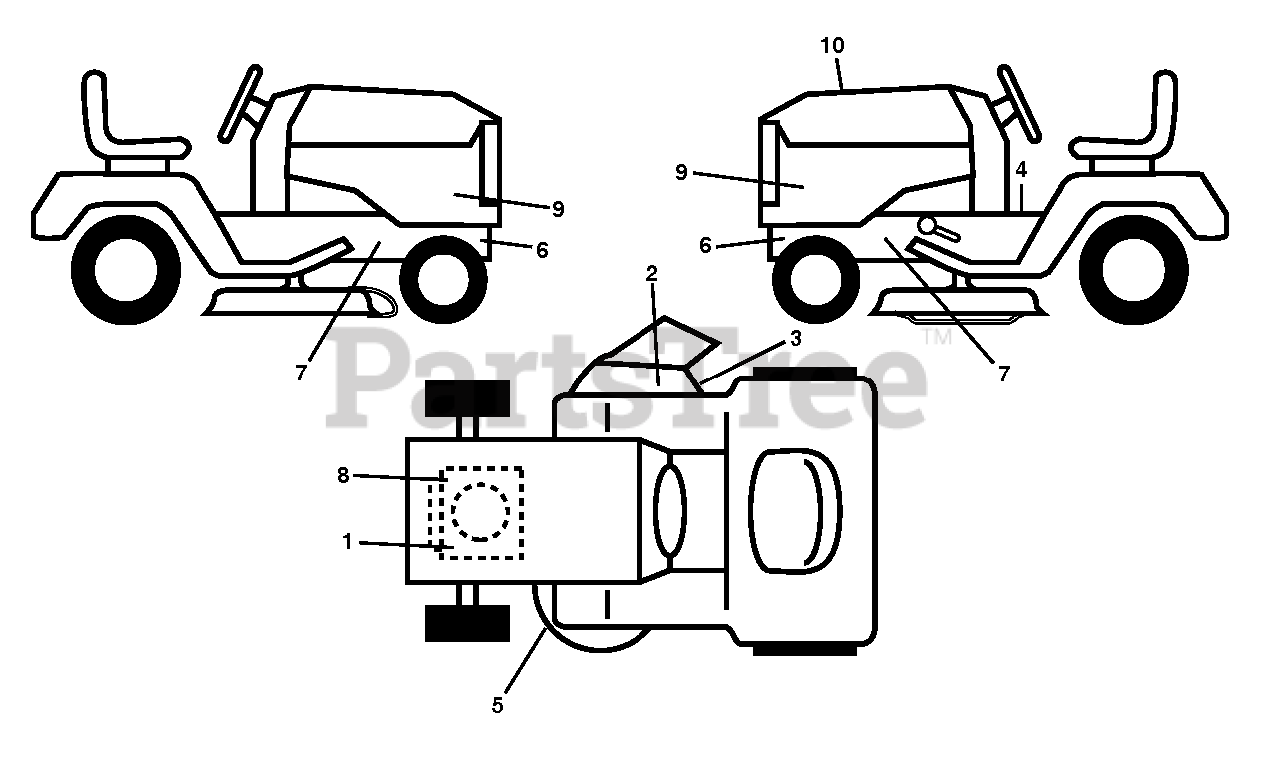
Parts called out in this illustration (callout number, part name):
1	DECAL.ENG.BS.656.ENDUR.382292
2	DECAL, DECK DEFLECTOR, WARNING
3	DECAL.DFLCTR.WARNNG.CTFNGR.SYM
4	DECAL TRACTOR SADDLE DECAL DEC
5	DECAL.V-BELT.SCH.42/46"MEC/ELE
6	DECAL.CHASSIS.HOT.MUFFLER
7	DECAL.WARNING.SERVCE/FIRE
8	DECAL.ENGINE.WARNING
10	DECAL.CHASSIS.HOT.MUFFLER
